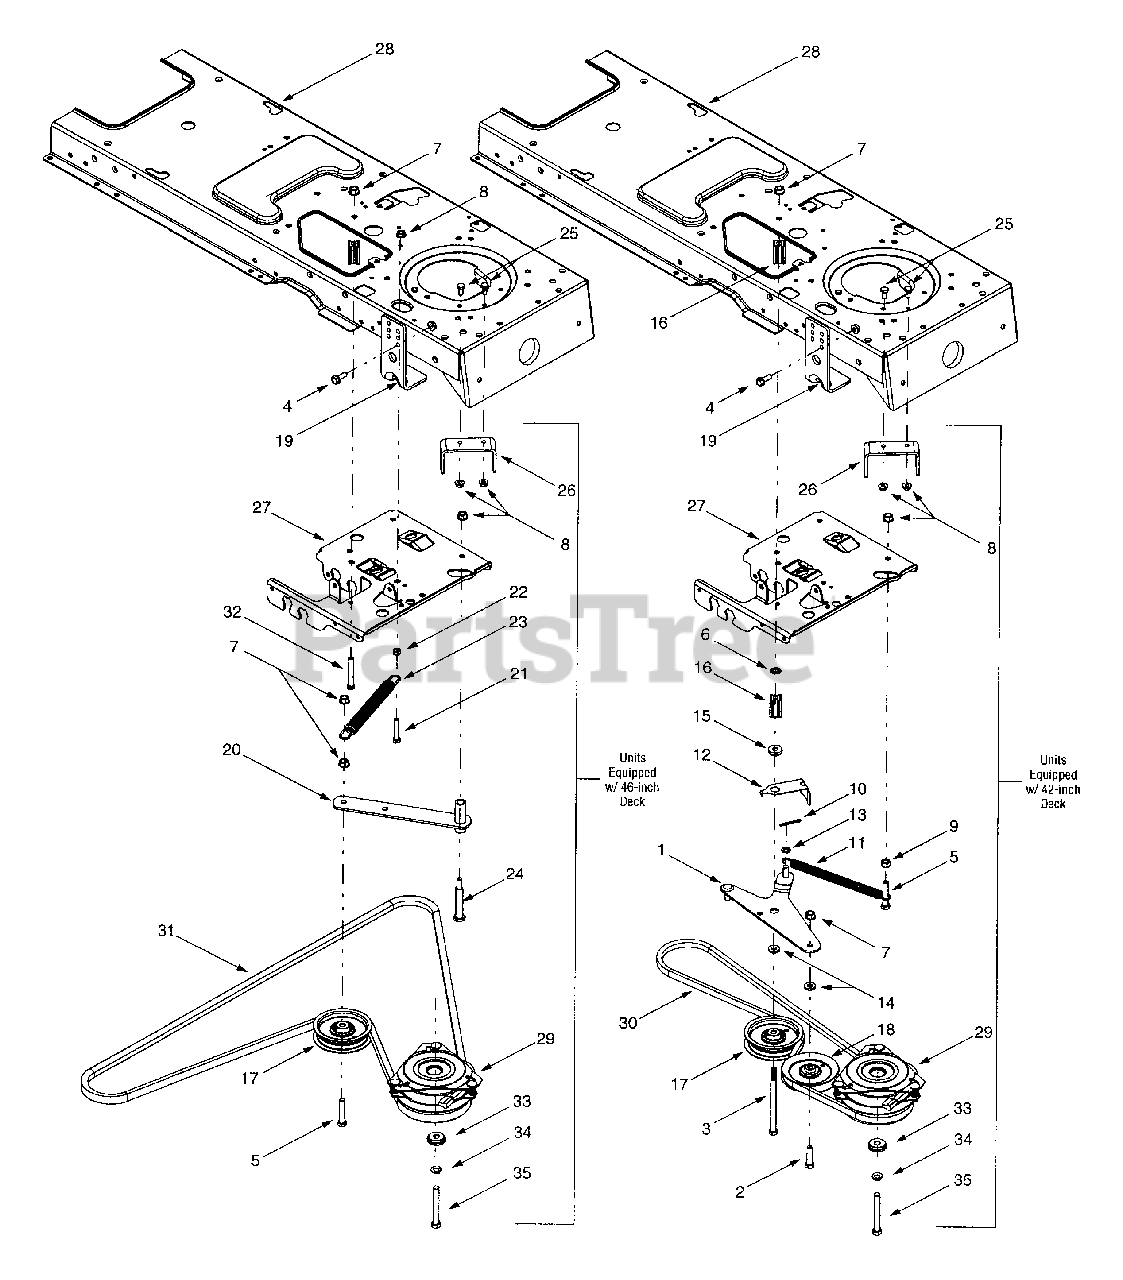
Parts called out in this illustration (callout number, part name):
3	Hex Cap Screw, 3/8-16 x 5.5
4	Hex Head Washer Screw, 5/16-18 x .875
5	Hex Cap Screw, 3/8-16 x 2.0
6	Push Nut, 3/8
7	Flange Lock Nut, 3/8-16
8	Flange Lock Nut, 5/16-18
9	Hex Nut, 3/8-16
10	Cotter Pin, 1/8 x 1.25
11	Extension Spring, .62 x 6.12
12	Belt Guard
13	Flat Washer, .385 x .62 x .063
14	Flat Washer, .407 x .812 x .135
15	Shoulder Spacer, .380
16	Spacer, 3/8 x 1.54
17	Idler Pulley, 3.5
18	Idler Pulley, 4.0
22	Hex Nut, 5/16-18
23	Extension Spring, .62 x 5.62
24	Shoulder Screw, 1/2 x 2.5
25	Hex Cap Screw, 5/16-18 x .625
30	PTO Belt
31	PTO Belt
32	Hex Cap Screw, 3/8-16 x 2.5
33	Shoulder Spacer, 1.38 x .445 x .36
34	Lock Washer, 7/16
35	Hex Cap Screw, 7/16-20 x 3.25 (Grade 5)
